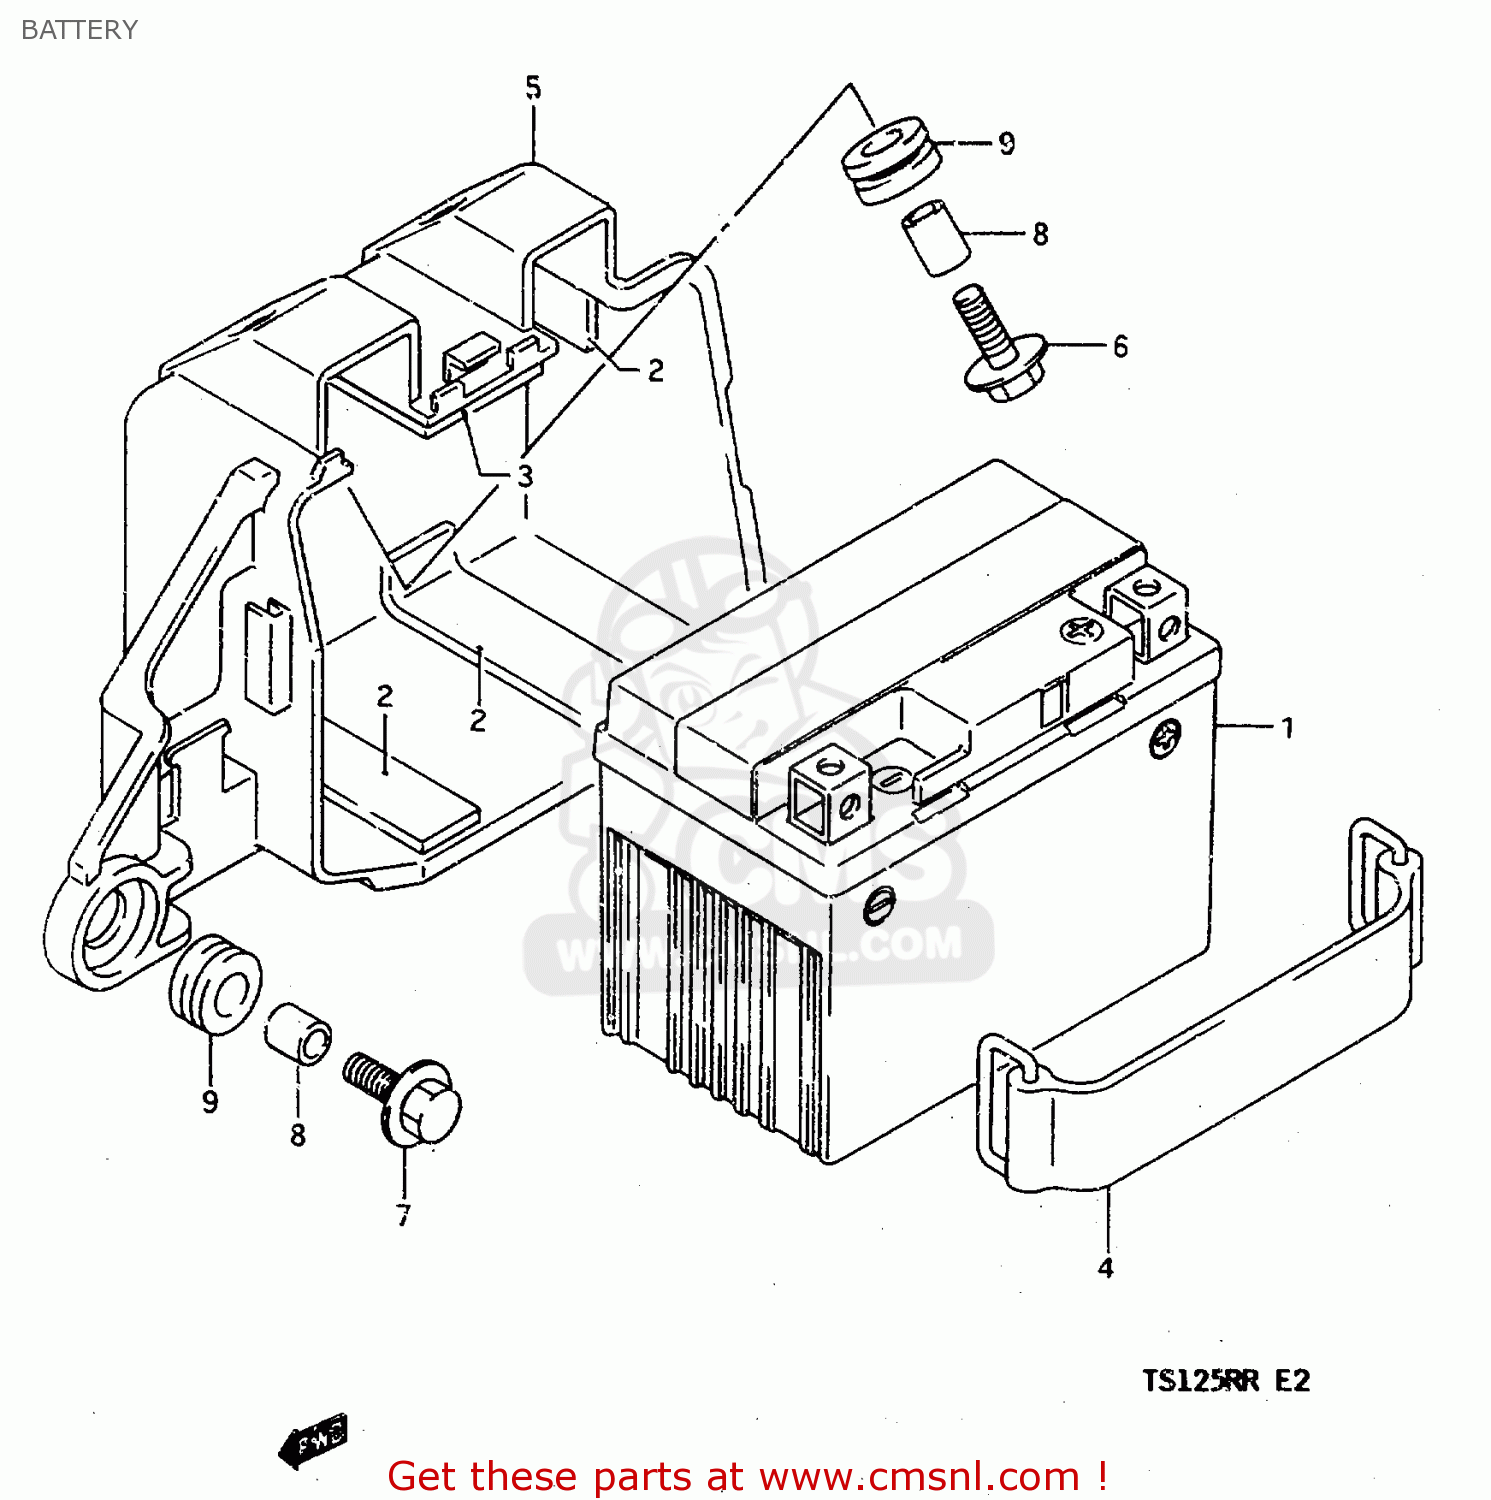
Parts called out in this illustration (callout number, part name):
1	BATTERY,YT4L-B
2	PROTECTOR,BATTERY
3	PROTECTOR,BATTERY
4	BAND
5	HOLDER,BATTERY
6	BOLT(6X16)
7	BOLT(6X20)
8	SPACER
9	CUSHION
